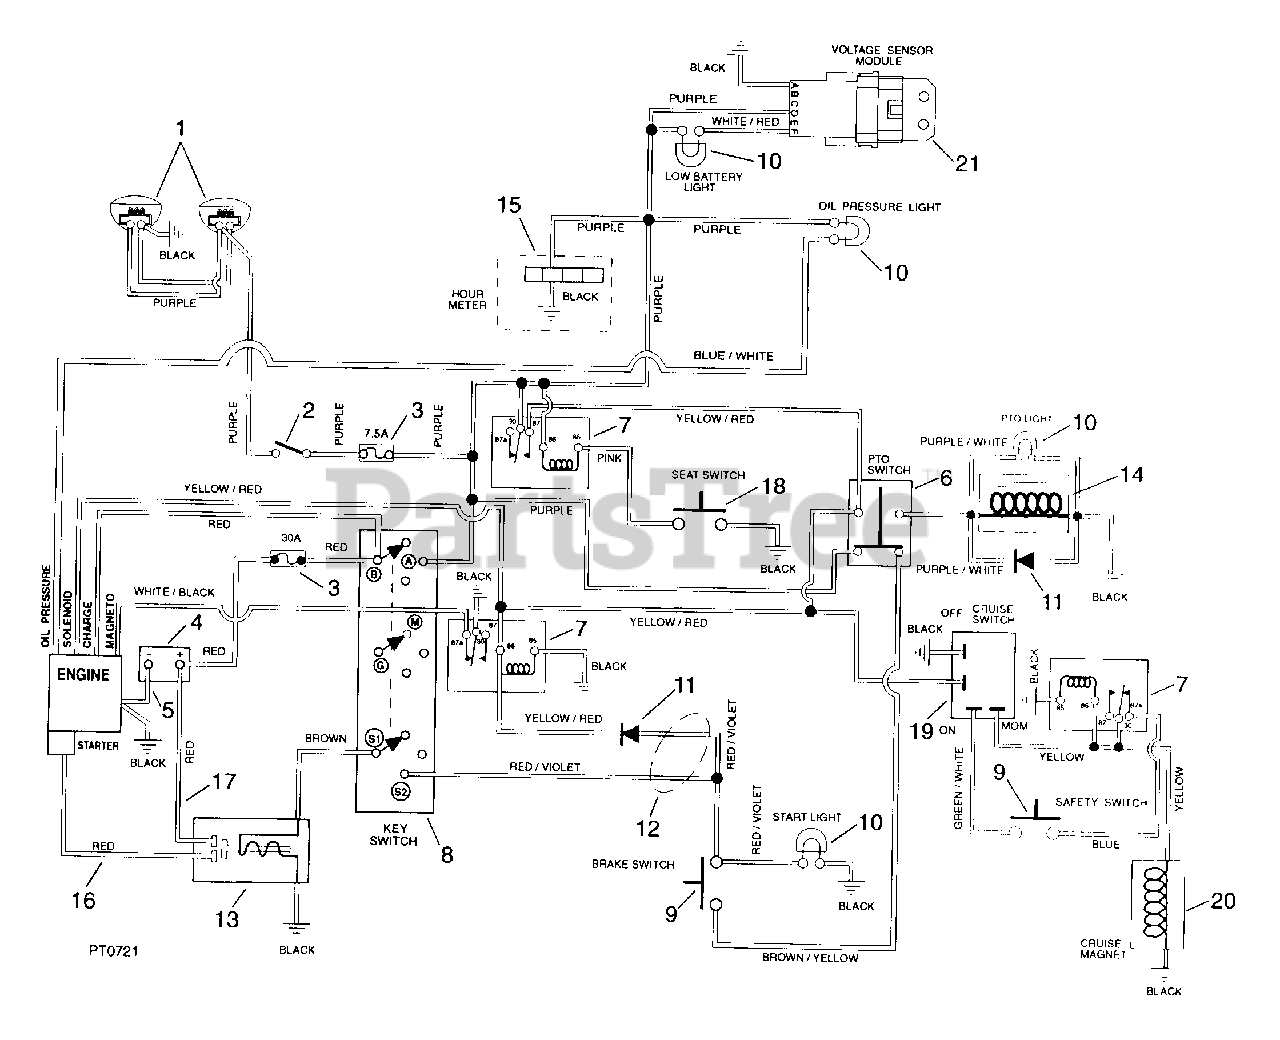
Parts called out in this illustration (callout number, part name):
1	HEADLIGHT- RH
1	HEADLIGHT- LH
2	SWITCH - LIGHT
3	7.5 AMP Fuse
3	30 AMP Fuse
4	BATTERY W/TUBE
5	GROUND CABLE .31X22.00X.31
6	PTO KNOB/ SWITCH ASSY
7	RELAY
8	KEY SWITCH
9	SWITCH- SINGLE POLE N.O.
10	#194 Bulb
11	MOLDED DIODE PLUG 1 AMP
12	WIRE HARNESS - 1640H B&S TWIN
12	WIRE HARNESS - 1648H B&S TWIN
13	SOLENOID
14	ELECTRIC CLUTCH/BRAKE (3.4AMP)
14	CLUTCH, ELECTRIC - WARNER
15	HOURMETER KIT- SIERRA
16	START CABLE 22"
17	STARTER CABLE 6.75"
18	SWITCH- SEAT
19	SWITCH - CRUISE
21	MODULE - VOLTAGE SENSOR
